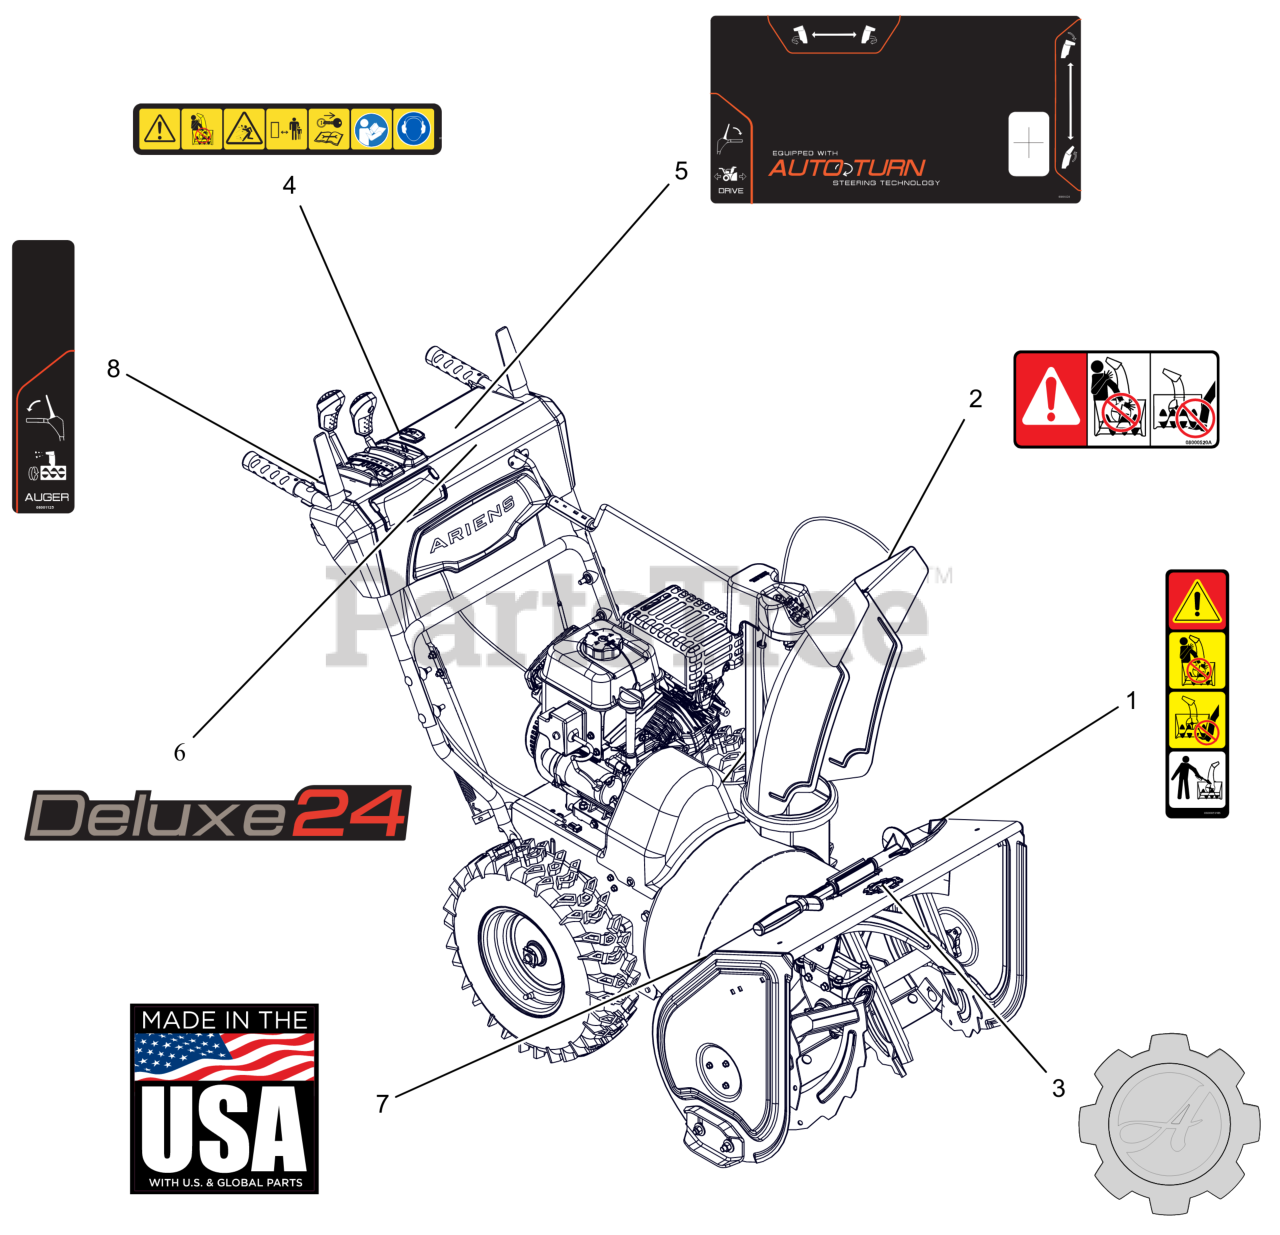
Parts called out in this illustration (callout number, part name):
1	DECAL, DANGER - ROTATING PARTS
2	DECAL, DANGER
3	DECAL, ARIENS-GEAR BADGE -THK
4	DECAL,DASH - SAFETY
5	DECAL,CONTROL-LG ID
6	DECAL, DASH - DELUXE 24
7	DECAL, MADE IN USA
8	DECAL,CONTROL-RH CONTROL
